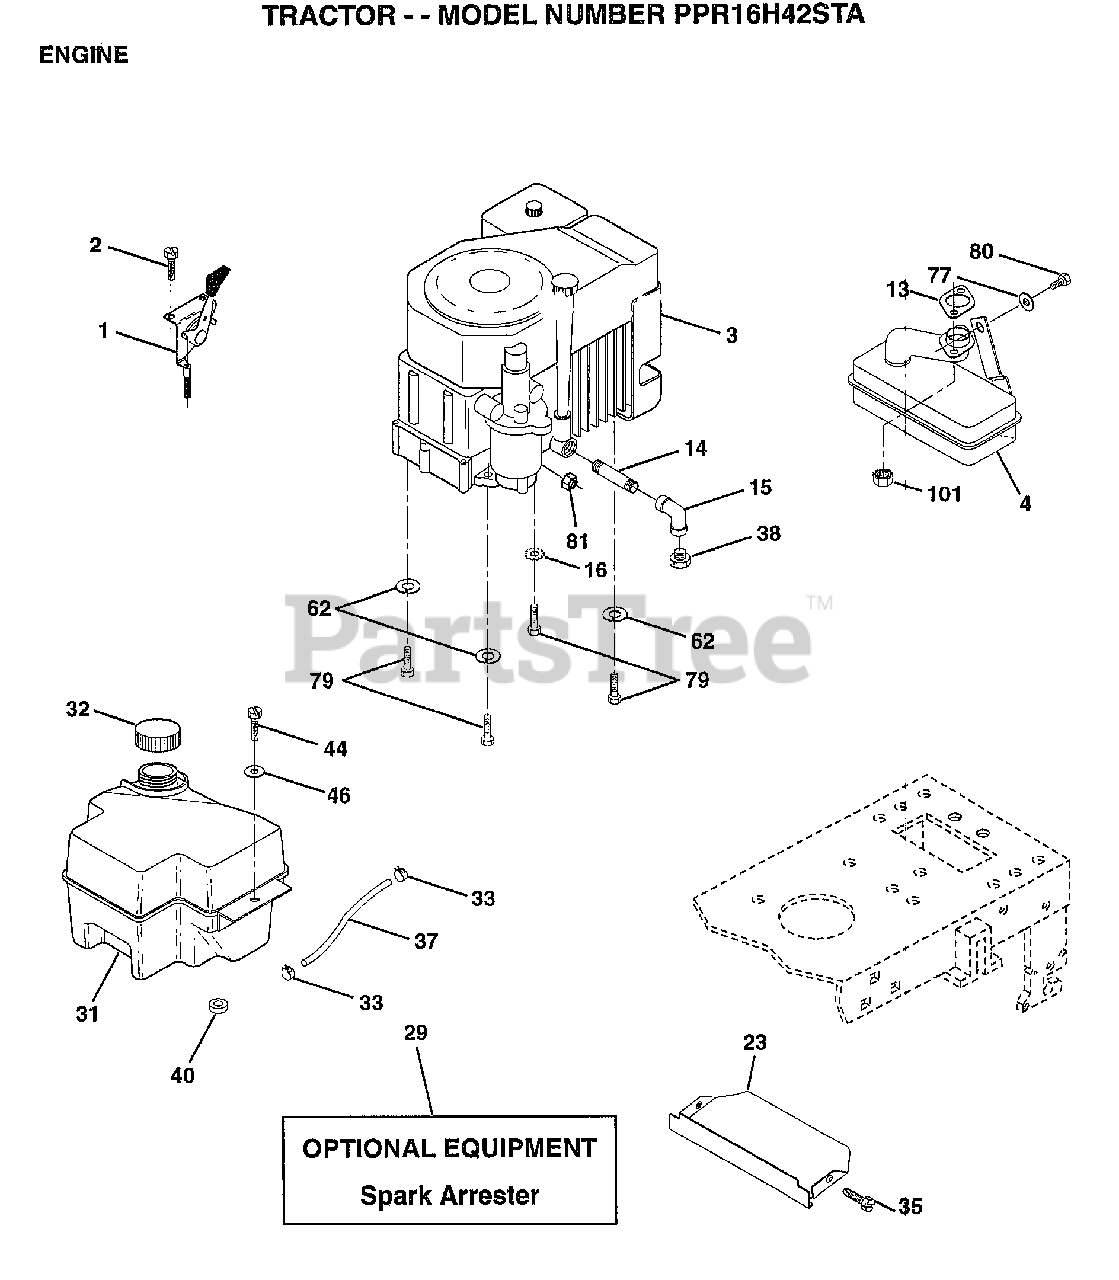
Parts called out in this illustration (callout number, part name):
1	CONTROL.THROTTLE/CHOKE
2	SCREW LT
4	MUFFLER
13	GASKET, EXHAUST MANIFOLD
14	PIPE NIPPLE
15	ELBOW
16	LOCKWASHER.5/16.E
23	SHIELD.BRN/DBR.GD
31	TANK.FUEL.FRONT.
32	CAP ASM FUEL
33	HOSE CLAMP
35	SCREW
37	LINE FUEL
44	SCREW HEX CRT
46	WASHER
62	LOCKWASHER
80	BOLT
81	NUT
101	NUT FLANGE M8-125
